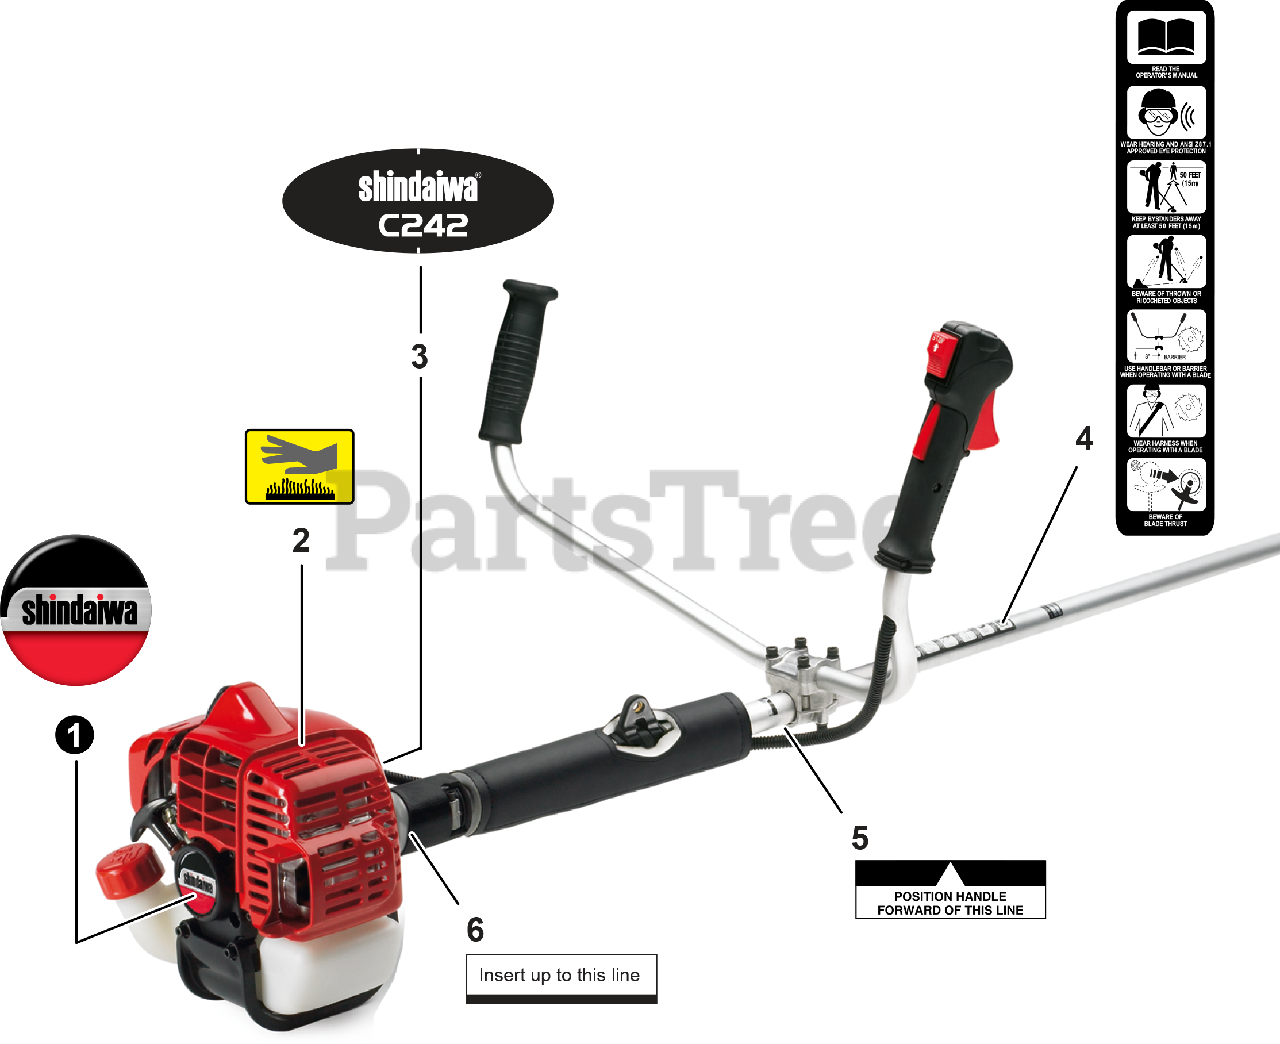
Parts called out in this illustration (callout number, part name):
1	LABEL, RECOIL STARTER
2	LABEL, CAUTION - HOT
3	LABEL, MODEL - C242
4	LABEL, CAUTION (BLADE CAPABLE)
5	LABEL, HANDLE
6	LABEL - ALIGNMENT
